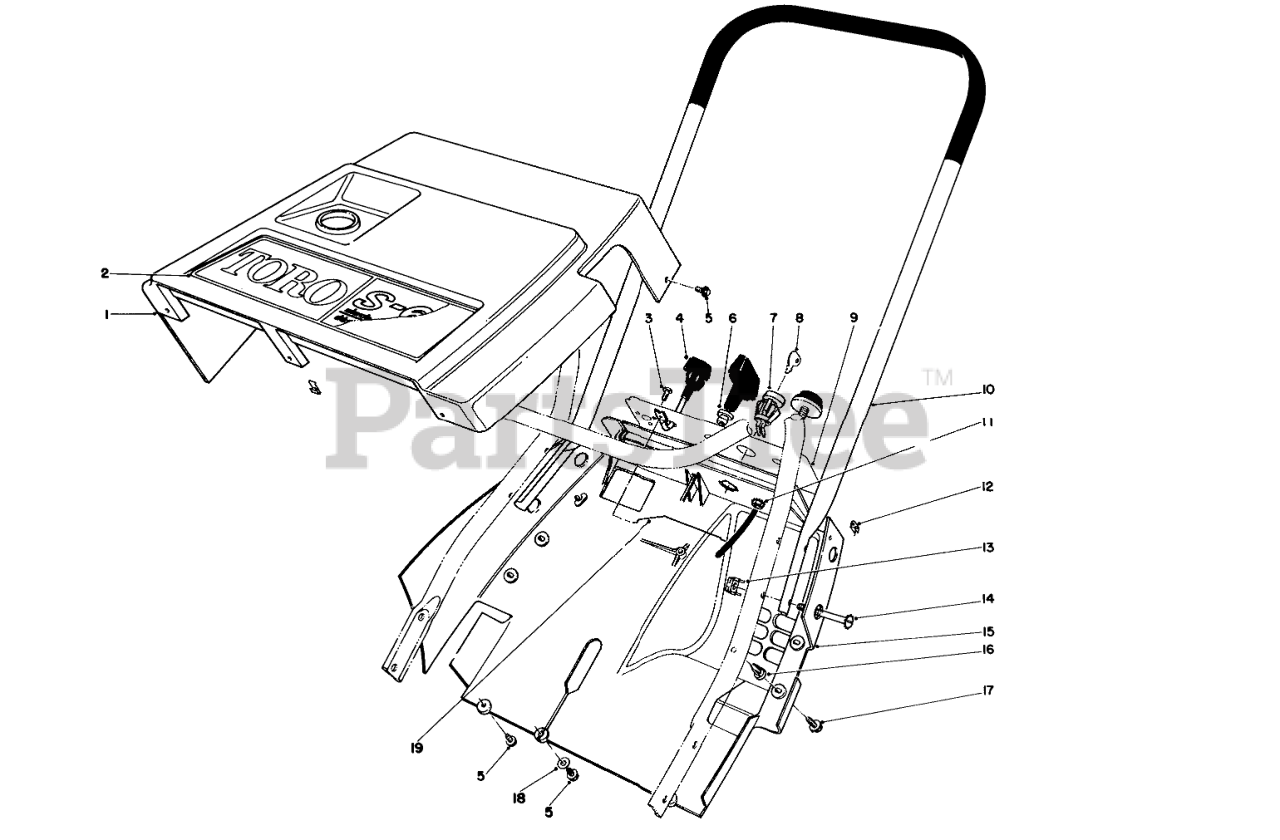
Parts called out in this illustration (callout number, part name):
1	Shroud-Upper
2	TORO DECAL
3	SCREW-PLASTITE
4	CHOKE CONTROL ASM
5	SCREW-HWHTF
6	GUIDE-ROPE, STARTER
7	SWITCH
8	Key
9	Decal-Control Panel
10	Handle-Upper
11	NUT-KEPS
13	TINNERMAN NUT
14	Sems Mach. Screw
15	LOWER SHROUD
16	Nut-Push In
17	SCREW-HWHTF
18	WASHER-FLAT
19	CONTROL WIRE
